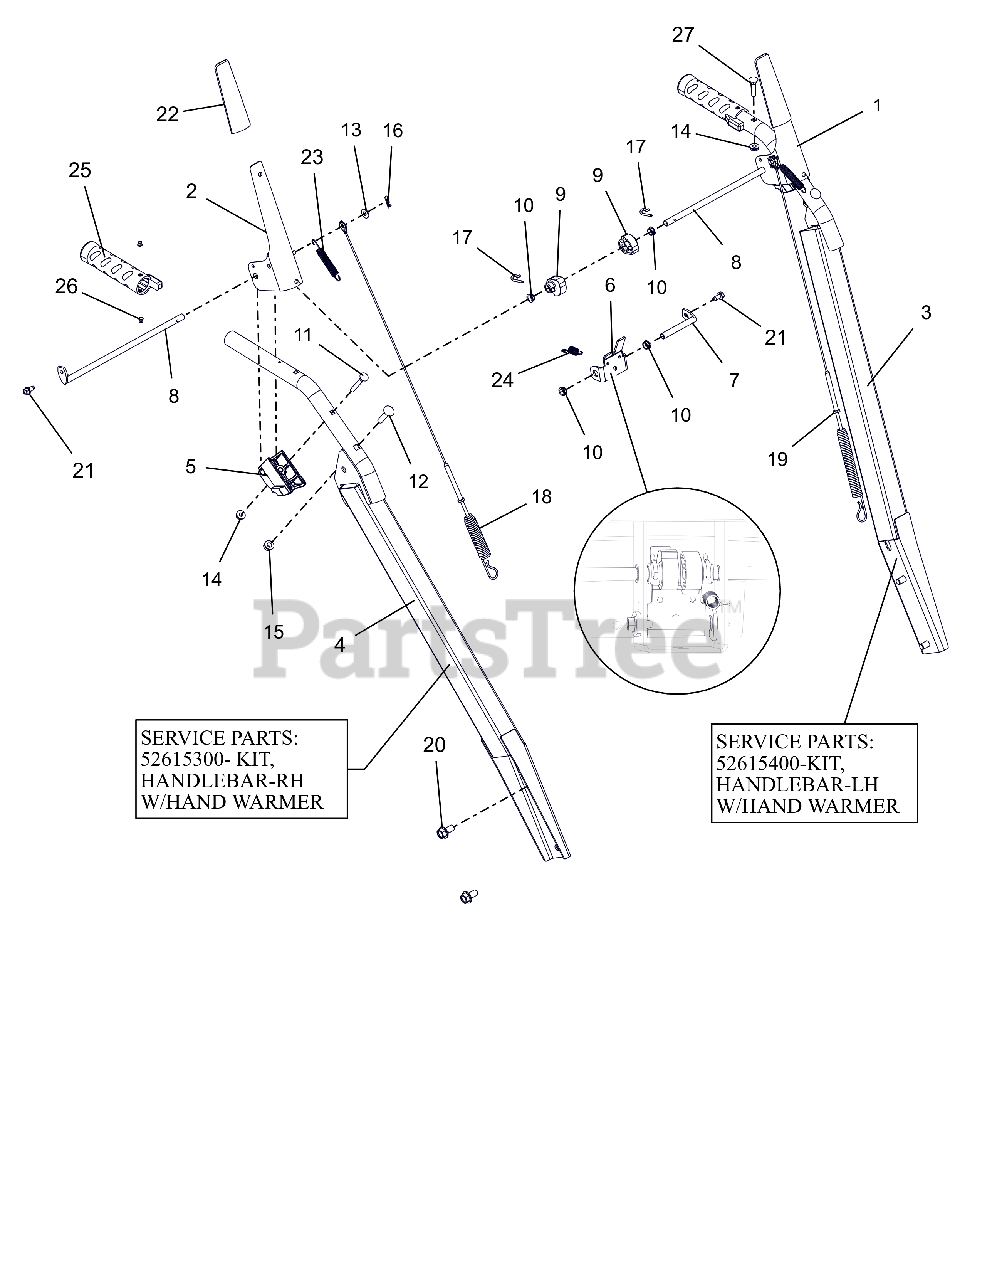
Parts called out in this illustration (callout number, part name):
1	LEVER, CLUTCH-LH
2	LEVER, CLUTCH-RH
3	HANDLEBAR, HEAVYDUTY-PRO LH
3	KIT, HANDLEBAR-LH W/WARM GRIP
4	HANDLEBAR, HEAVYDUTY-PRO-RH
4	KIT, HANDLEBAR-RH W/WARM GRIP
5	BLOCK, CLUTCH PADDLE
6	BRACKET, INTERLOCK ARM
7	ROD, PIVOT - INTERLOCK
8	ROD, PADDLE MOUNT - PRO
9	CAM, INTERLOCK
10	BUSHING, POLYLINER-.38 SNAPIN
11	BLT-RDHDXLSQNK .25-20X2.0 G5YZ
12	BLT,RHSN .31-18X1.50 G5 ZCC
13	WSHR,FLT .281X.625X.065 ZCC
14	NUT-LK-CTR-FLG .25-20 ZC120
15	NUT-LK-TOP-FLG .312-18 GF ZCC
16	PIN, HAIR #178 .06X.77 ZCC
17	PIN, SPRING CLIP
18	CABLE, AUGER (DELUXE & PRO)
19	CABLE, UPPER TRACTION
20	BLT-SERHFWH .38-16X.75 YWZC
21	SCR-TAP .25-20X.50 HWH ZCC
22	SLEEVE, CLUTCH PADDLE-GRAY
23	SPRING, EXTENSION
24	SPRING-EXT .047X.438X1.45
25	GRIP,HEATED HANDLE-GRAY
26	RVT-POP #43 .125X.313 STL ZINC
27	BLT-RDHDXLSQNK.25-20X1.25 G5ZC
